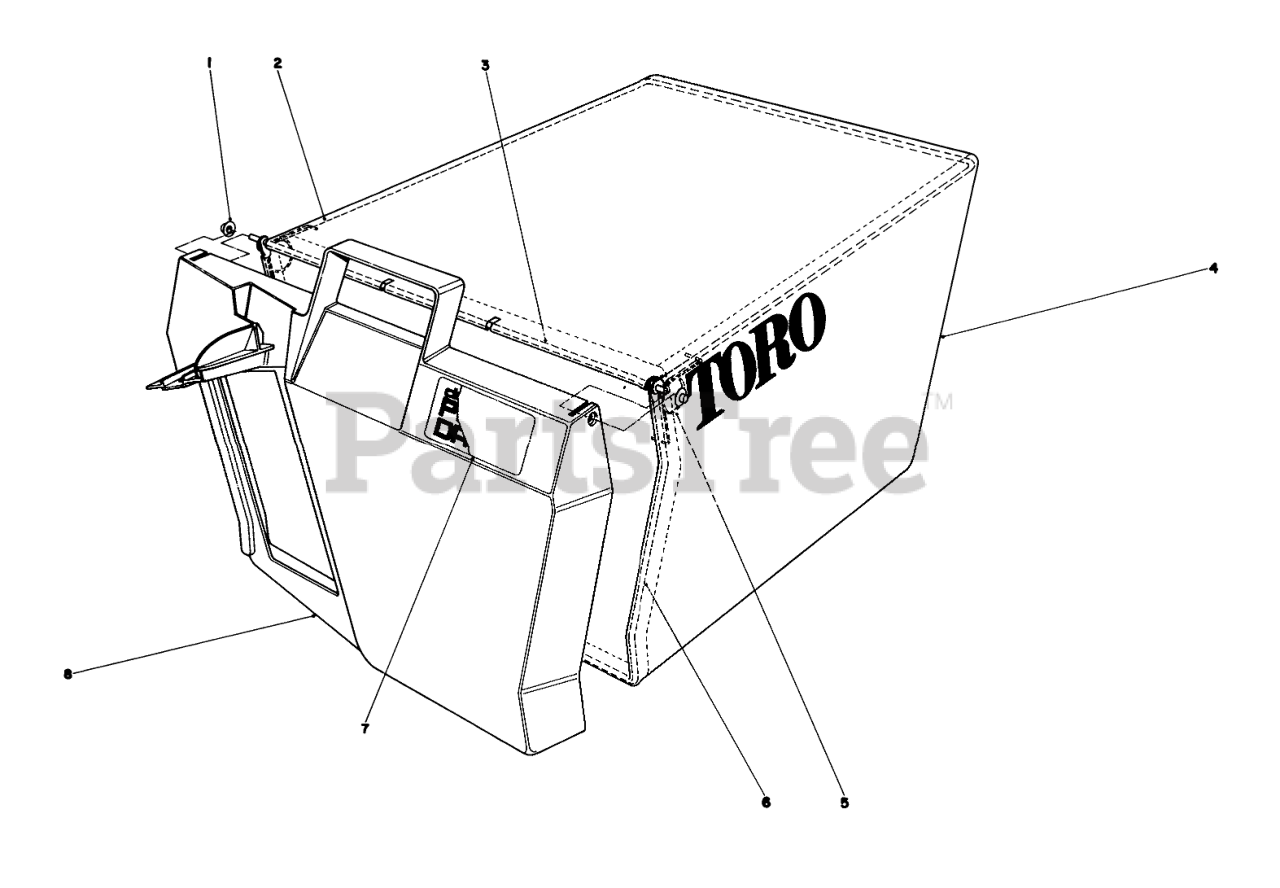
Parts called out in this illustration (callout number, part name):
1	NUT-PUSH
2	Bag Frame Upper
3	HINGE-DOOR, BAG
4	Bag
5	SPRING
6	Frame Bag
7	Decal Bag Door
8	Door Grass Bag
